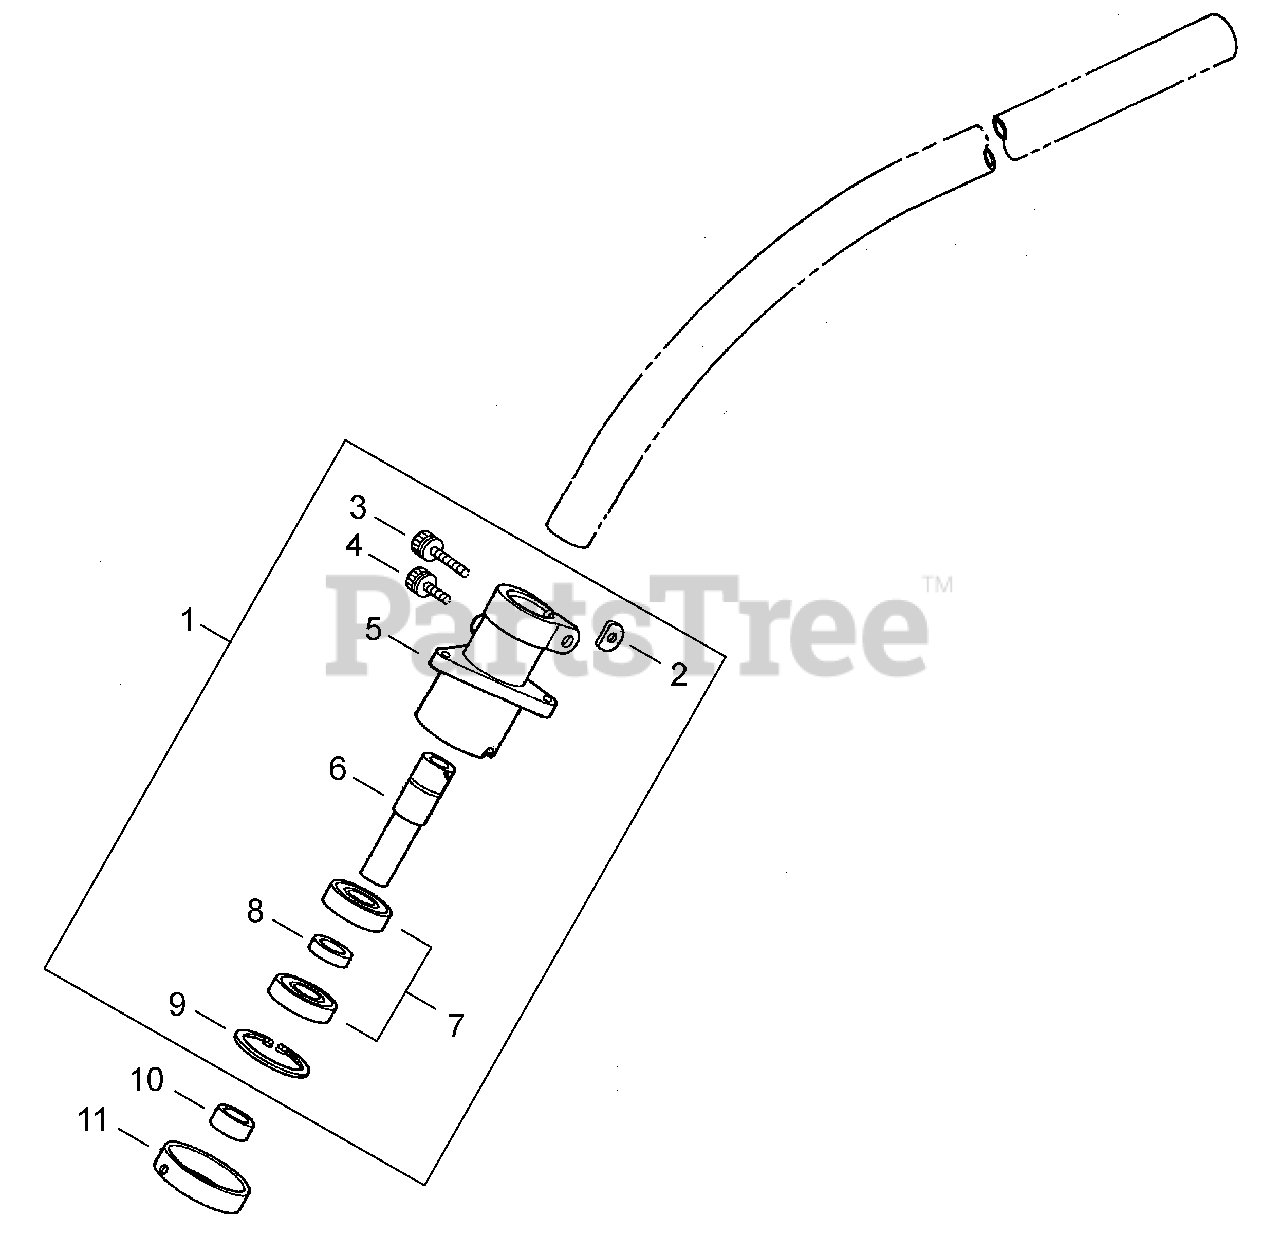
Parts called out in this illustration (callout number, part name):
1	GEAR CASE ASSY
2	SHIM
3	SCREW - 5X25
4	SCREW - 5X10
5	CASE, GEAR
6	SHAFT
7	BEARING, BALL - 6001DDU
8	COLLAR (A)
9	RING, RETAINING - 28
10	SPACER - LOWER
11	HOLDER
